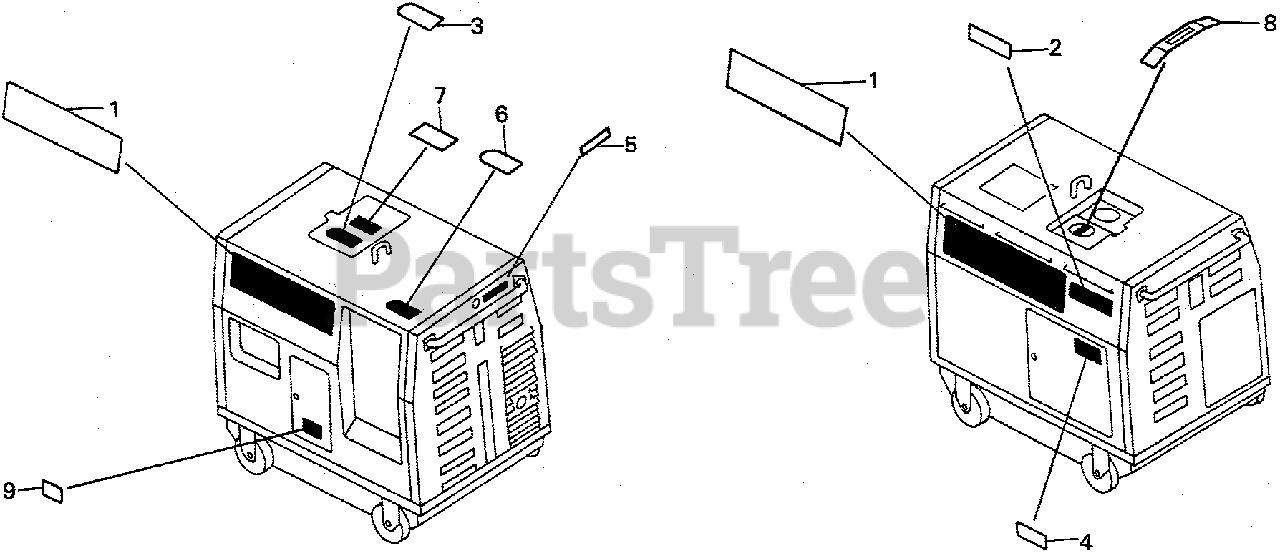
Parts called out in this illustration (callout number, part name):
1	EMBLEM, MAIN
2	PLATE, CAUTION
3	MARK, CAUTION (ENGLISH/FRENCH)(SPANISH)
4	MARK, AIR CLEANER
5	MARK, EX. CAUTION
6	MARK, CAUTION (CO)(ENGLISH/FRENCH)(SPANISH)
7	LABEL, CONNECT WARNING (ENGLISH)
8	MARK, FUEL METER
9	MARK, OIL CAUTION
